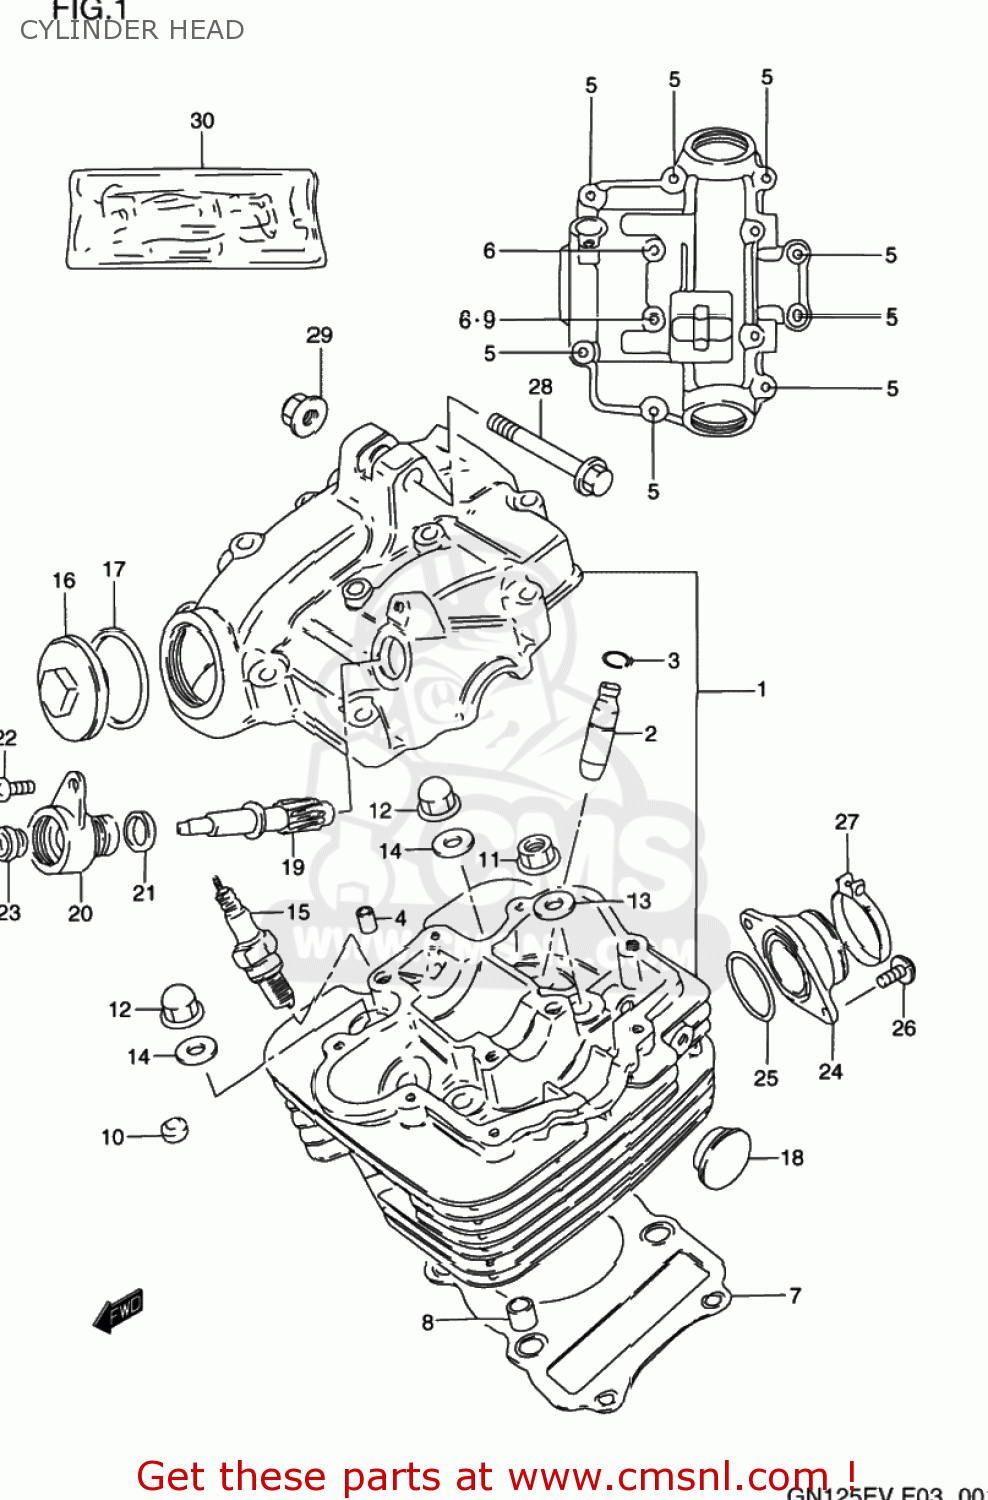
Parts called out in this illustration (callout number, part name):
1	HEAD ASSY,CYLINDER
2	GUIDE,VALVE
3	RING,SNAP
4	PIN(6.2X8X11)
5	BOLT
6	BOLT
7	GASKET,CYLINDER HEAD (NAS)
8	PIN
9	GASKET(5.8X13X1.2) (NAS)
10	PAD,CYLINDER HEAD
11	NUT
12	NUT
13	WASHER(8.5X19X2.3)
14	GASKET(8.5X17X2.3) (NAS)
15	SPARK PLUG D8EA
16	CAP,INSPECTION HOLE
17	O RING(D:3,ID:29.5)
18	PLUG(OD:22.5)
19	GEAR,TACHOMETER DRIVEN
20	SLEEVE,TACHOMETER DRIVE GEAR
21	SEAL,TACHOMETER DRIVEN
22	SCREW(5X12)
23	SEAL,OIL(5X12X8)
24	PIPE,INTAKE
25	O RING(D:2.4,ID:31.7)
26	SCREW
27	CLAMP
28	BOLT(8X50)
29	NUT
30	GASKET SET (NAS)
